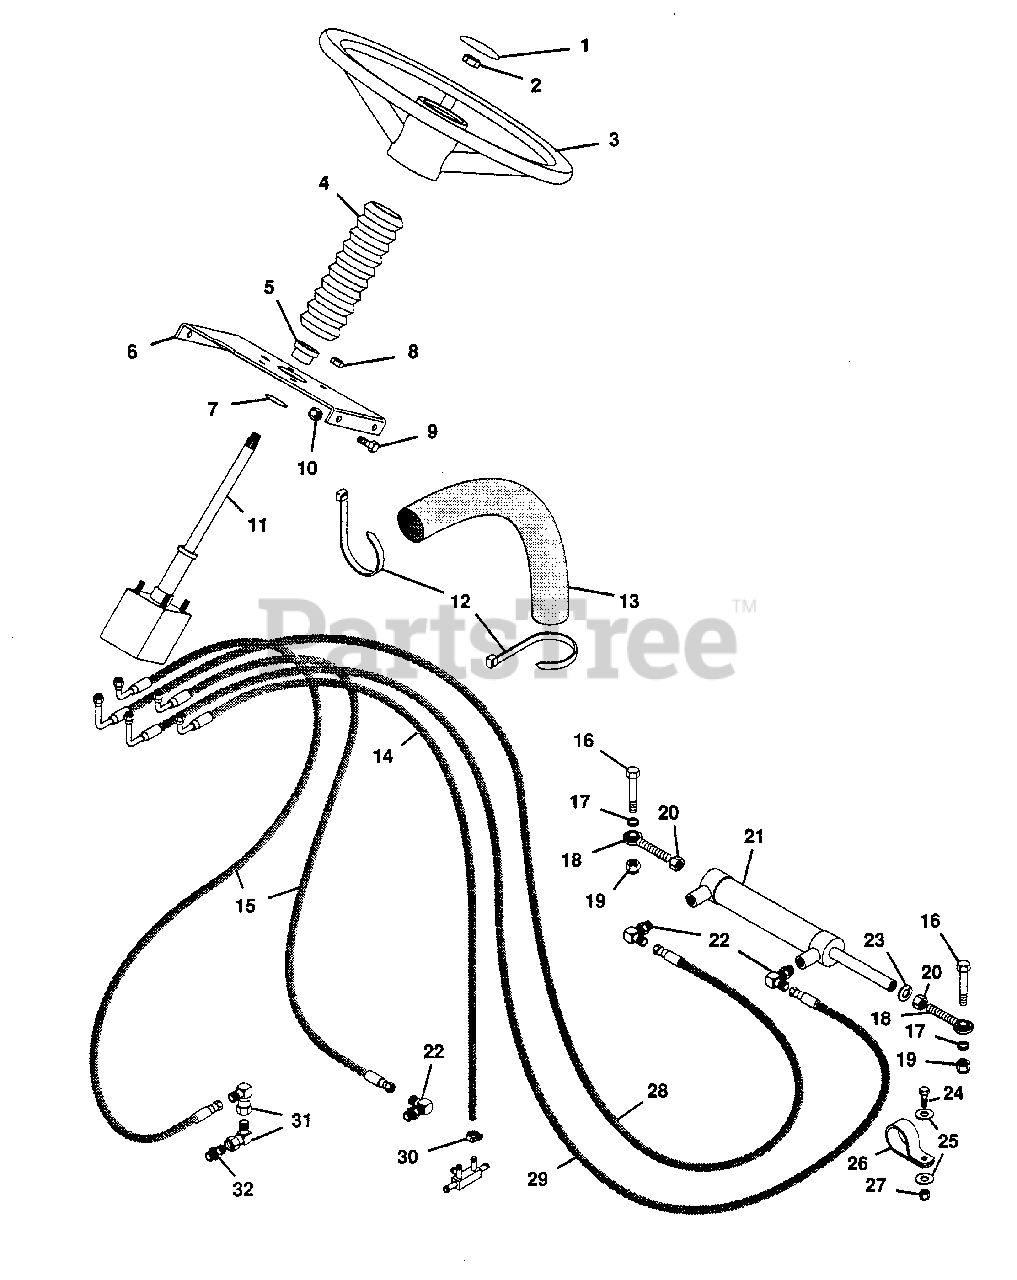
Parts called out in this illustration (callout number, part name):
1	Cap, Steering Wheel
2	Nut, Jam 5/8-11 Hex
3	Wheel, Steering
4	Bellows, Steering Wheel
5	Bush., Flg. .764x1.47x.560 Ny.
6	Bracket, Steering Pump
7	Ring, Retaining Int. Th. 1.00 Sft.
8	Nut, Lock 5/16-24
9	Bolt, Hex 5/16-18x.75
10	Nut, Lock 5/16-18
11	Power Steering Unit
12	Tie Wrap, Black
13	Sleeve, Protective
14	Assembly, Hydraulic Hose
15	Assembly, Hydraulic Hose
16	Bolt, Hex 1/2-13x2.00
17	Bush., St. .520x.625x.125 Stl.
18	Assembly, Rod End R.H.
19	Nut, Lock 1/2-13
20	Nut, Jam 1/2-20
21	Cylinder, Steering
22	Adapter, PH 2503-6-6
23	Washer, Lock 1/2 Reg.
24	Bolt, Hex 3/8-16x1.00
25	Washer, Flat .406x.812x.065
26	Clamp, Nylon
27	Nut, Lock 3/8-16
28	Assembly, Hydraulic Hose
29	Assembly, Hydraulic Hose
30	Clamp Hose
31	Adaptor, PH 3903-6-6
32	Adaptor, PH 0503-6-6
